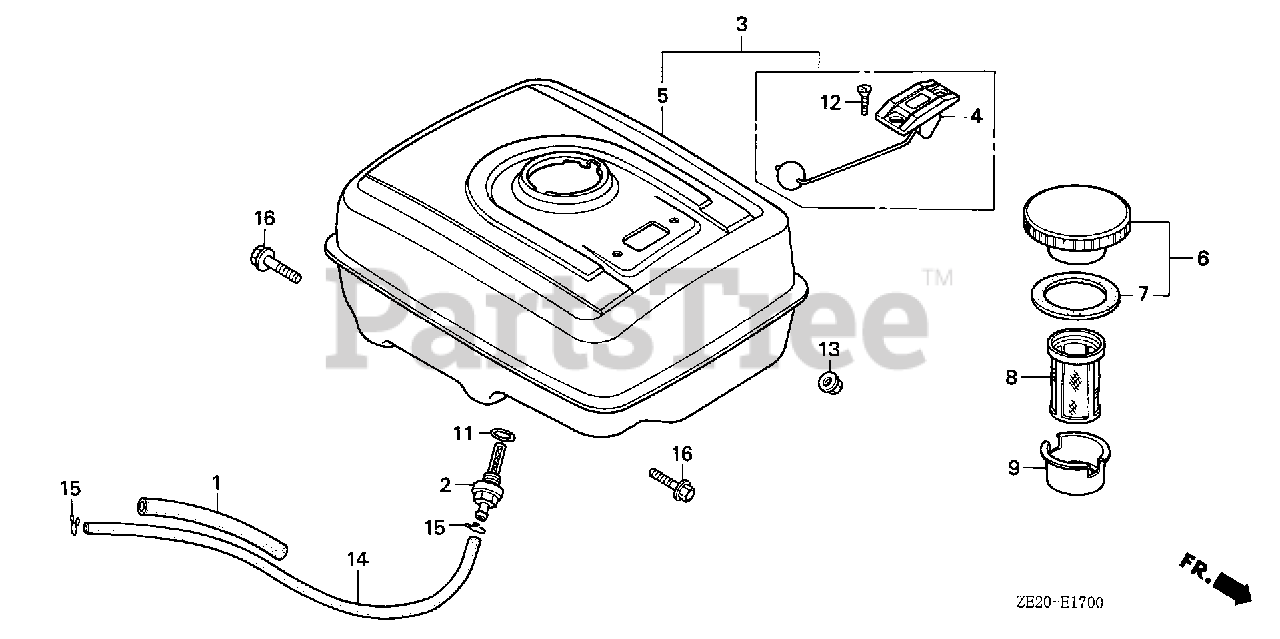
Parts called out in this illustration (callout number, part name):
1	RUBBER, SUPPORTER (107MM)
2	JOINT, FUEL TANK (NOT AVAILABLE)
2	JOINT, FUEL TANK
5	TANK, FUEL *NH31* (MCKINLEY WHITE)
6	CAP, FUEL FILLER (BLACK)
7	GASKET, FUEL FILLER CAP (39X58X3)
8	FILTER, FUEL
9	HOLDER, FUEL FILTER
11	O-RING (14MM) (ARAI)
11	O-RING (14MM) (NOK)
13	NUT, FLANGE (8MM)
14	BULK HOSE, FUEL (4.5X3000) (4.5X222)
15	CLIP, TUBE (B8)
16	BOLT, FLANGE (8X25)
